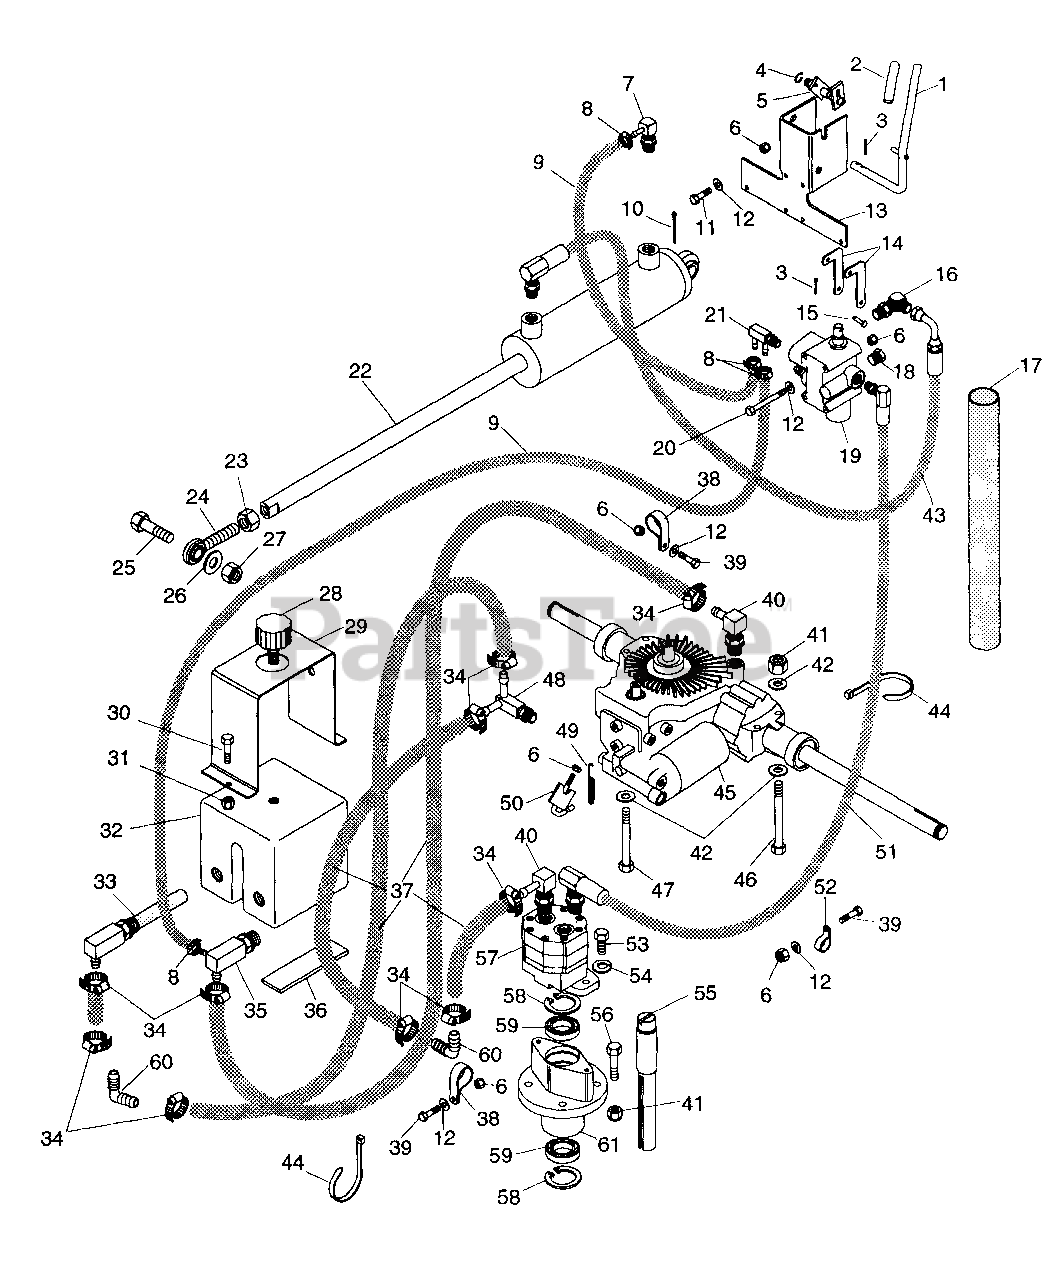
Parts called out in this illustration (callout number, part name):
1	Weldment, Lever
2	Grip, PTO Lever
3	Pin-Cotter .09 x .75
4	Ring-Retaining-External .392 x .042
5	Weldment, Linkage
6	Nut-Locking-Nylon .250-20
7	Fitting adapter .562-18
8	Clamp-Hose .78 x .44 x 1.17
9	Hose, Hydraulic
10	Pin-Cotter .12 x 1.25
11	Bolt-Hex .25-20 x .75 Grade 5
12	Washer-Flat-Steel .281 x .620 x .065
13	Bracket
14	Rod, Hydraulic Control
15	Pin-Clevis .189 x 1.0
16	Adapter 2503-6-4
17	Sleeve, Protective
18	Plug .44-20
19	Valve, Hydraulic
20	Bolt-Hex .25-20 x 3.00
21	Fitting-Pipe .563-18
22	Cylinder
23	Nut-Jam .50-20
24	Assembly, Rod End
25	Bolt-Hex .50-13 x 1.75
26	Washer-Flat-Steel .531 x 1.062 x .095
27	Nut-Locking-Nylon .50-13
28	Cap, Filter
29	Strap, Tank
30	Bolt-Hex .31-18 x .75 Grade 5
31	Nut-Locking-Nylon .312-18
32	Tank Hydraulic
33	Fitting, Filter
34	Clamp, .88 Dia. Hose
35	Fitting with O-Ring 88-14 x .268
36	Pad, Gas Tank
37	Hose
38	Clamp,Steel 1.0
39	Bolt-Hex .25-20 x .875
40	Fitting
41	Nut-Locking-Nylon .375-16
42	Washer-Flat-Steel .406 x .812 x .065
43	Assembly, Pressure Hose
44	Tie Wrap. Black
45	Filter, Oil
46	Bolt-Hex .38-16 x 4.00
47	Bolt-Hex .38-16 x 3.25 Grade 5
48	Fitting-Pipe .875-14
49	Spring-Tension .061 x .50 x 3.5
50	Weldment Lever
51	Assembly, Pressure Hose
52	Clamp, Cushioned Steel
53	Bolt-Hex .38-16 x .75 Grade 5
54	Washer-Lock .375 x .094
55	Shaft
56	Bolt-Hex .38-16 x 1.50 Grade 5
57	Pump Hydraulic
58	Ring-Retaining-Internal 2.210 x .062
59	Bearing-Ball 1.0 x 2.0 x .56
60	Elbow-Barbed .63 x .63
61	Housing
